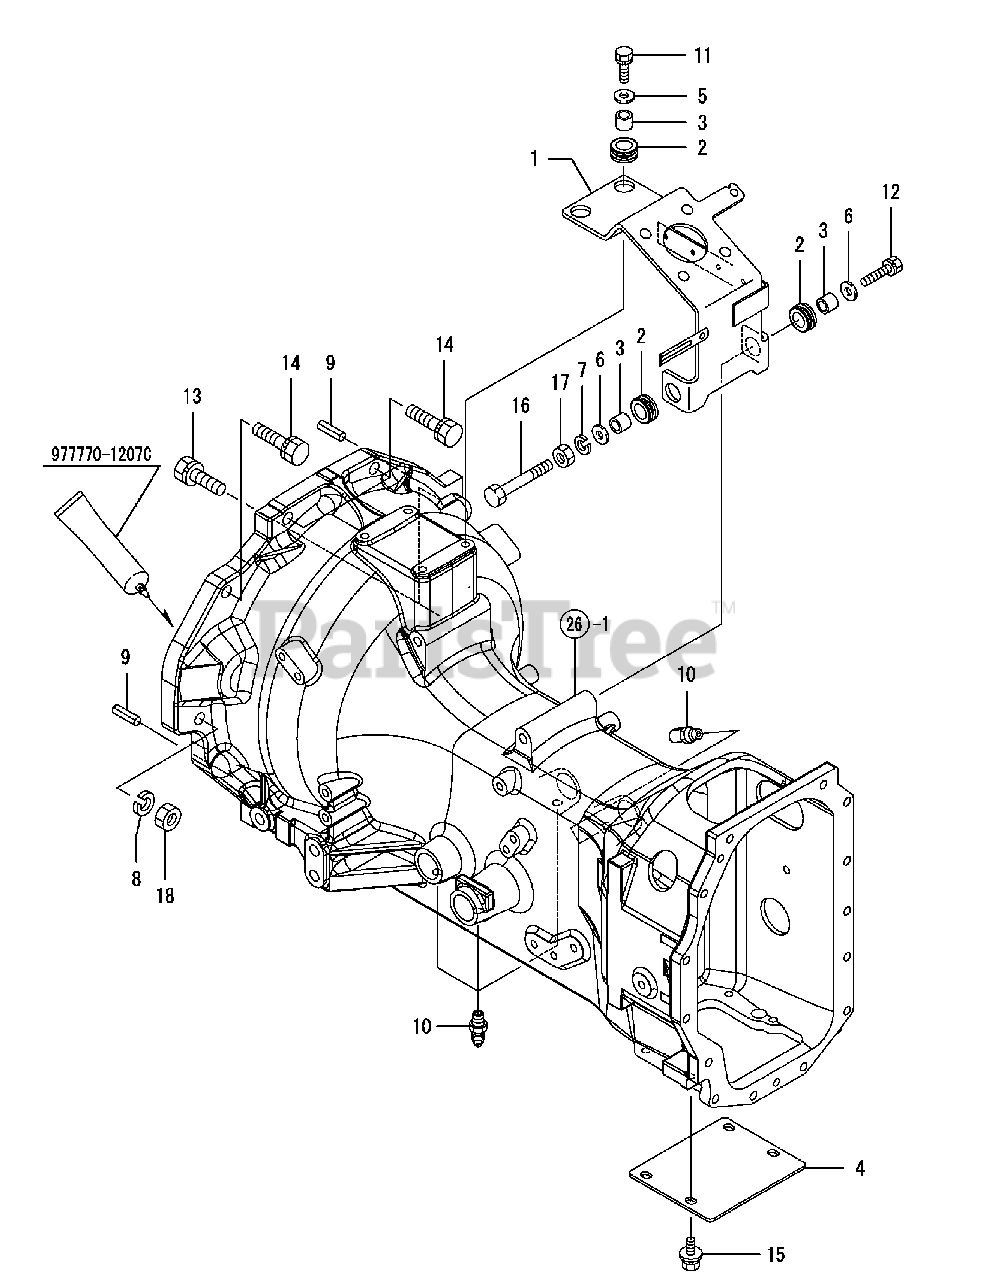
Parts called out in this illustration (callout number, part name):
1	Stay Cmp, Gear Box
3	Collar 10.6X13.8X12.5
7	Spring Washer 10
8	Spring Washer 12
9	Spring Pin 8X16
10	Nipple B,Grease
16	Bolt M10X 80 Plated
